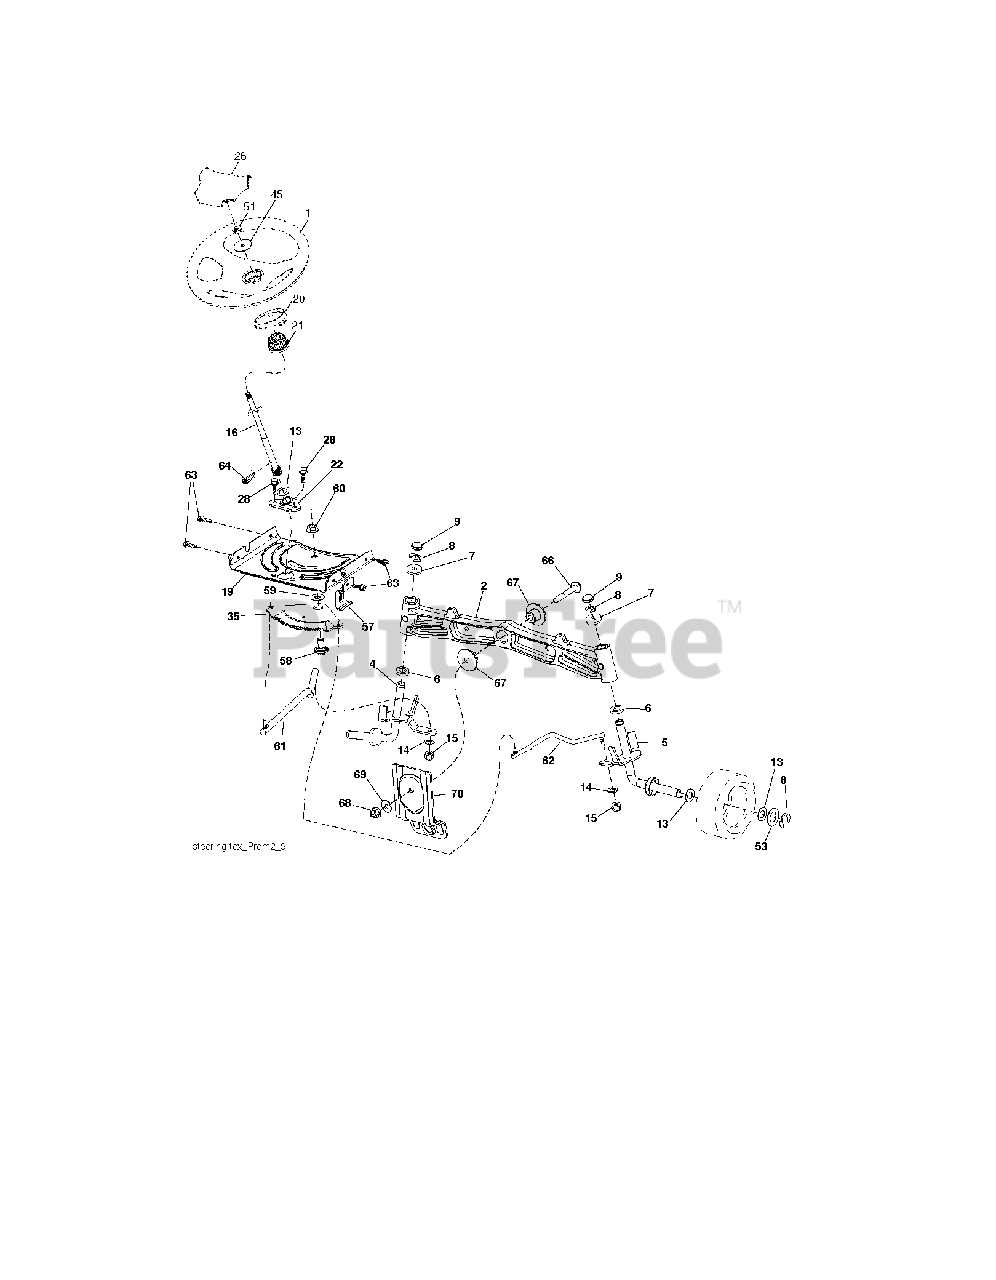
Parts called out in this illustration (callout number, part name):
1	WHEEL.STEERING.MLT.BR.YEL/OVRM
2	AXLE.CAST.IRON
4	SPINDLE.WELDED.LH.15"TEX
5	SPINDLE.WELDED.RH.15"T
8	RING CLIP
9	CAP.SPINDLE.BLACK
14	WASHER, LOCK 3/8
15	NUT CROWNLOCK 3/8-24
16	SHAFT, STEERING
19	PLATE.STEER.DDL.NLT/NG
20	CAP.WHL.STRNG.MULTI.BRND.YEL
21	ADAPTER, WHEEL STNG..
22	STEERING.SUPT.LOWER.
26	CAP.WHL.STRNG.MULTI.BRND.YEL
28	SCREW, 3/8-16X3/4
35	GEAR.SECTOR.PLATE.DDL.
45	WASHER 9/16"ID, 2 3/8""OD
51	NUT.HEX.1/2-20
53	WASHER.HARDENED
57	BRKT.UPSTOP.GT/LT.TEX
58	BOLT.SHOULDER.SECTOR.P
59	WASHER.THURST.SECTOR.S
60	NUT FLANGE LOCK 5/8-11
61	DRAGLINK.LH.BALLSTUD.D
62	DRAGLINK.RH.BALLSTUD.D
63	SCREW
64	RETAINER.CLIP.SPRING.S
66	BOLT HEX FGHD 7/16-14 X 3 SERR
67	BUSHING.PM.FRONT AXLE
68	NUT.LOCK.FLANGE.7/16
69	WASHER.1.5X.505X.118
70	BRKT.DECK.SUSPENSION.F
